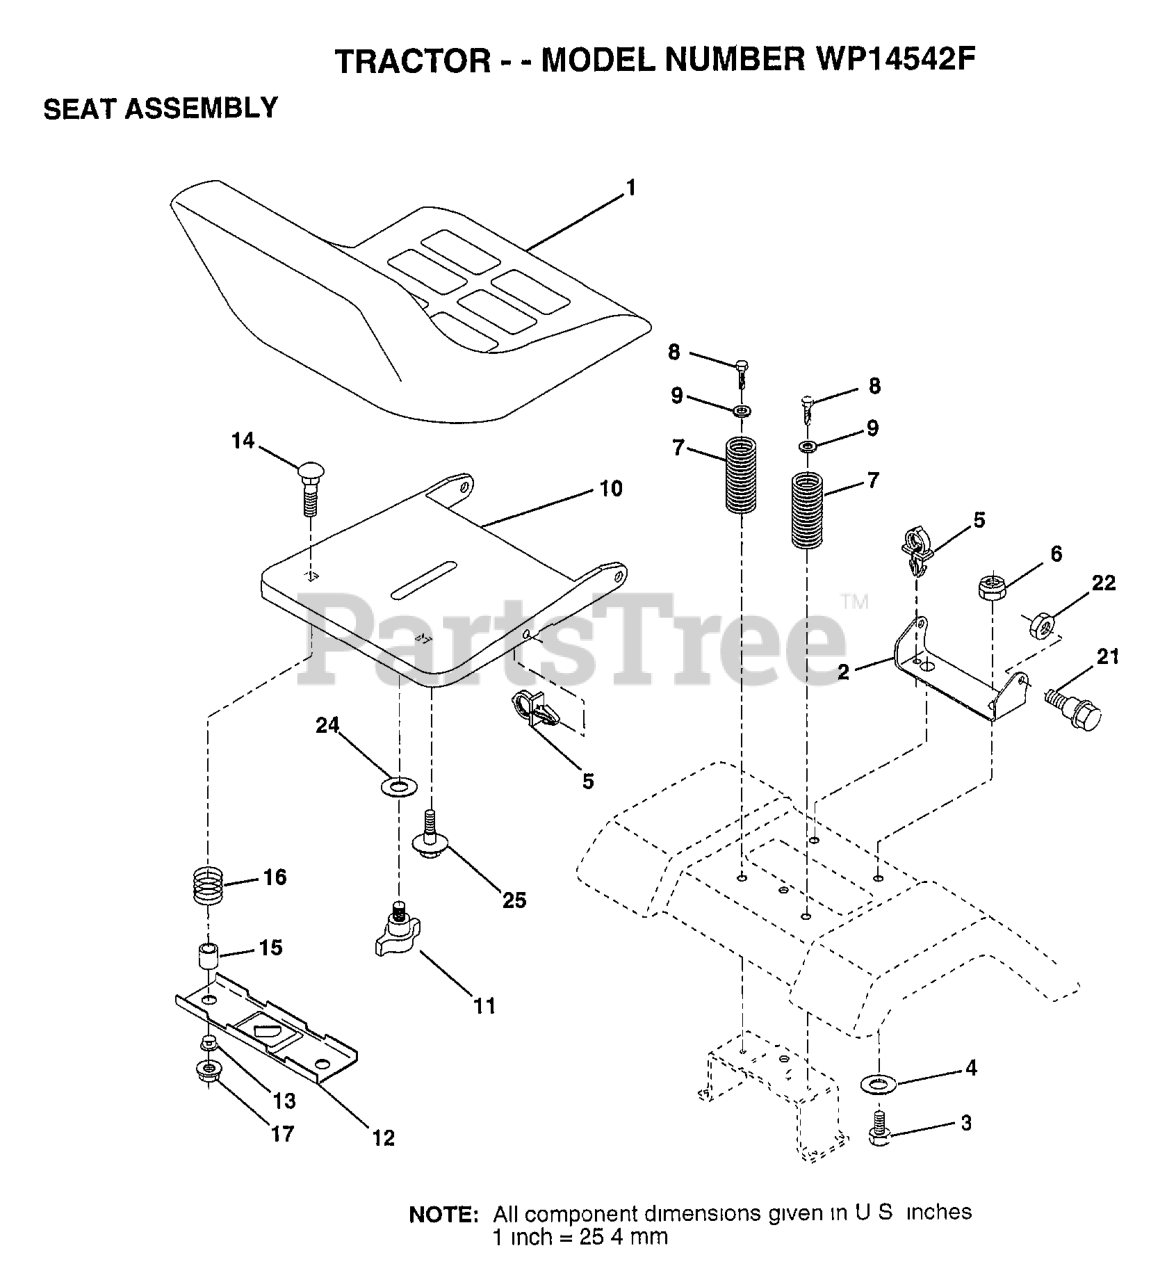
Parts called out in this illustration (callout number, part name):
1	SEAT
2	BRKT,SEAT PIVOT**
3	BOLT
6	NUT
7	SPRING COMPRESSION
8	SCREW GTV
9	WASHER
10	PAN, SEAT
11	KNOB.SEAT.ADJ.WINGNUT
12	BRKT SWITCH
14	BOLT.ROUND.HEAD.SQUARE.NECK
15	SPACER SPLIT 28X.96
17	NUT T
21	BOLT SHOULDER 5/16-18
22	LOCKNUT
25	BOLT, SHOULDER**
